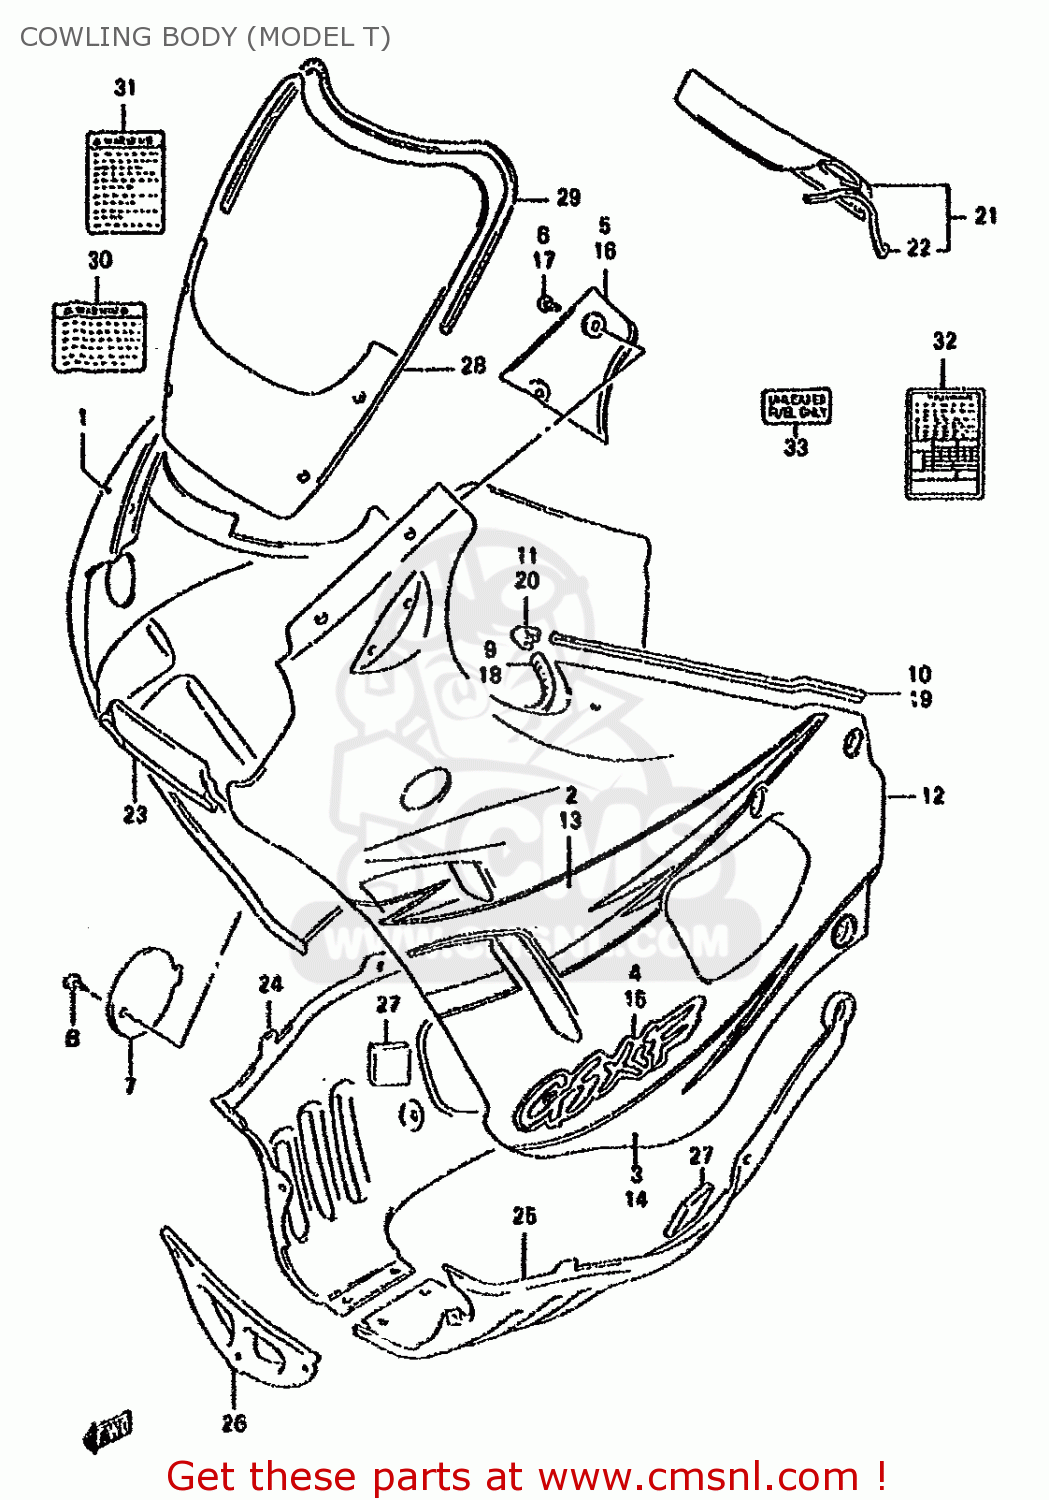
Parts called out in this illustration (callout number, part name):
1	COVER ASSY,COWLING,R
2	TAPE,BODY COWL SIDE UPR,R
3	TAPE,BODY COWL SIDE LWR,R
4	EMBLEM,BODY COWL SIDE
5	COVER,METER SIDE,RIGHT
6	SCREW
7	LID,OIL
8	SCREW(6X16)
9	MOLD,COWLING
10	MOLDING
11	JOINT,MOLDING END
12	COVER ASSY,COWLING,L
13	TAPE,BODY COWLING SIDE,UPPER
14	TAPE,BODY COWL SIDE LWR,L
15	EMBLEM,BODY COWL SIDE
16	COVER,METER SIDE,L(GREEN)
17	SCREW
18	MOLD,COWLING
19	MOLDING
20	JOINT,MOLDING END
21	COVER,METER
22	MOLDING
23	PANEL,COWLING CTR
24	COVER,COWLING,UNDER,RIGHT
25	COVER,COWLING,UNDER,LEFT
26	COVER,COWLING UNDER FR
27	CUSHION,UNDER COWLING
28	WINDOW,COWLING
29	MOLDING,WINDSCREEN
30	LABEL,WARNING
31	LABEL (WARNING SCREEN)
32	LABEL, TIRE AIR
33	LABEL,CAUTION
55	COVER,COWLING UNDER,L
56	SCREW(6X30)
57	WASHER(6.5X18X1.5)
58	BRACKET,COWLING LWR,R
59	BRACKET,COWLING LWR,L
60	CUSHION
61	NUT,COWLING,FR
62	BOLT
63	SCREW(5X14)
64	WASHER(5.2X14X1.5)
65	NUT,HEADLAMP HOUSING,UPPER
66	SCREW(6X25)
67	WASHER(6.5X18X1.5)
68	SPACER(6.1X9X12.3)
69	CUSHION
70	SCREW(6X20)
71	SPACER (6.1X9X9)
72	CUSHION
73	SCREW, LOWER
74	BRACKET,FR UNDER COWL
75	SCREW
76	WASHER(5.2X14X1.5)
77	LABEL (WARNING SCREEN)
78	COVER,COWLING UNDER FR
79	LABEL (WARNING SCREEN)
80	LABEL, WARNING SAFETY
83	SCREW 6X12
